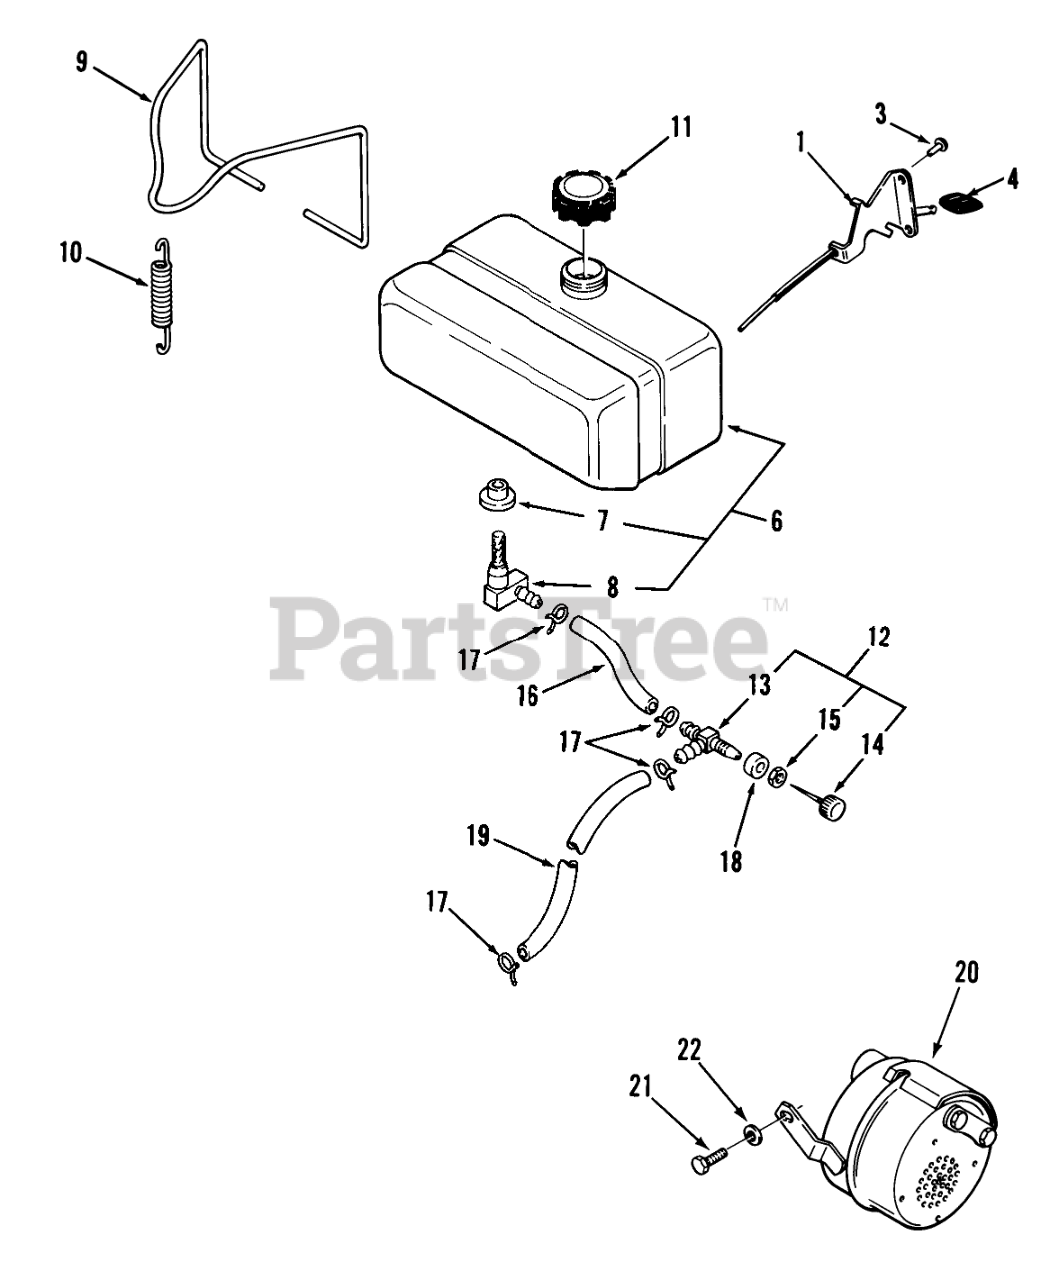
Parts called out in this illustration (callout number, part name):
1	Assy-Choke/Throttle Control
3	RIVET-4
4	KNOB-THROTTLE
6	ASSY-FUEL TANK
7	BUSHING
8	FITTING FUEL TANK
9	Hold Down Wire
10	SPRING-EXTENSION
11	CAP-GASOLINE
12	S/A FUEL VALVE
13	VALVE BODY
16	Fuel Hose 3.8 in. (9.7 cm)
17	Clamp
18	SPACER
19	Fuel Hose 18"
20	ASSY-MUFFLER
21	Bolt
